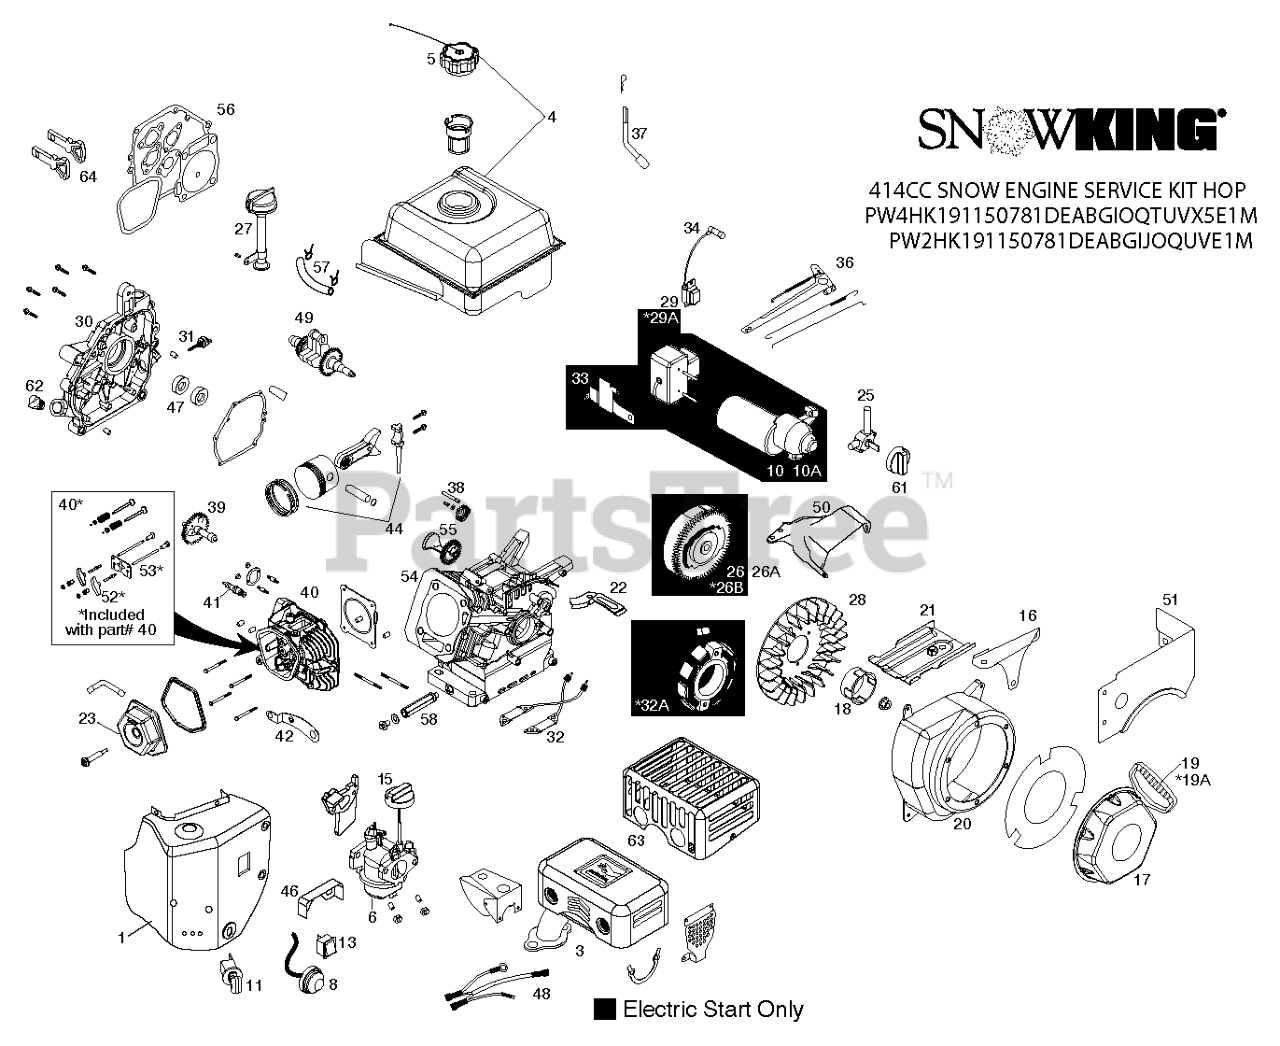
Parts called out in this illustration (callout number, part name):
1	HEATER.BOX.ASSY-SNW(SKSN4100)
3	MUFFLER.ASSY.SNOW(SKSN4200)
4	FUEL.TANK.ASSY.SNOW(SKSN4300)
5	FUEL.TANK.CAP.SNOW(SKSN4301)
6	CARBURETOR.ASSY.SNOW(SKSN4302)
8	PRIMER.BULB.ASSY(SKSN4304)
10	ELEC.START.ASSY.SNOW(SKSN4400)
10A	STARTER EUROPEAN 230V ELECTRIC
11	KEY.SWITCH.ASSY.SNOW(SKSN4401)
13	ON/OFF.SWITCH.SNOW(SKSN4403)
15	CHOKE.KNOW.SNOW(SKSN4500)
16	PLATE.GOVERN.LINK.S
17	RECOIL.START.ASSY.SNW(SKSN4600
18	STARTER.CUP.SML.SNOW(SKSN4601)
19	STARTER.GRIP.SNOW(SKSN4603.1)
20	BLOWER.HSG.ASSY.ELEC(SKSN4602
21	SHIELD.CYLINDER.SNOW(SK4141010
22	SHIELD.U/FYWHL.CHARG(SKSN4604)
23	VALVE.COVER.LCT.414CC.
25	FUEL.PETCOCK.SNOW(SKSN4900)
26	FLYWHEEL.ASSY.ELEC.START
26A	FLYWHEEL.ASSY.MAN.START
27	HIGHOIL.FILL.ASSY.KIT(SKSN4911
28	FLYWHEEL.FAN(SK4144000)
29	IGNITION.COIL.(CDI).291-414CC
30	CRANKCASE.CVR.ASSY(SK4143600)
31	DIPSTK.OIL.BLK.LCTSK4143711.1
32	CHARGING.COIL.AC/DC(SK4141710)
33	ELECTRIC.START.BRKT(SKSN4405)
34	SPARK.PLUG.BOOT.SNW,SKSN4691.1
36	GOVERNOR.ARM.ASSY(SKSN4502)
37	GOVERNOR.SHAFT(SK4143100)
38	GOVERNOR.GEAR.ASSY(SK4142900)
39	CAMSHAFT(SK4141600)
40	CYL.HEAD.ASSY.45 DEG.NON-GEN
41	SPARK.PLUG(SK2911550)
42	CDI.BOX.BRKT.SNOW(SKSN4402)
44	PISTON.AND.ROD.ASSY(SK4141400)
46	SHIELD.VAPOR(SKSN4606)
47	OIL SEAL KIT NON-GENERATOR
48	WIRE.HARNESS(SKSN4406)
49	CRANKSHAFT.KEYED
50	RP TOP SHIELD
51	SKIRT FUEL TANK
52	ROCKER ARM KIT
53	PUSH ROD TAPPET KIT
54	CYLINDER ASSY
55	COUNTER WEIGHT KIT
56	KIT.ENGINE GASKET.LCT.414CC
57	FUEL HOSE KIT
58	EXTENDED OIL DRAIN TUBE
61	FUEL KNOB-SNOW
62	NONREMVABLE.OIL.PLUG(SK4143715
63	CE COMPLIANT MUFFLER SHEILD
64	KEY SET(2 KEYS) SKSN0407.1
